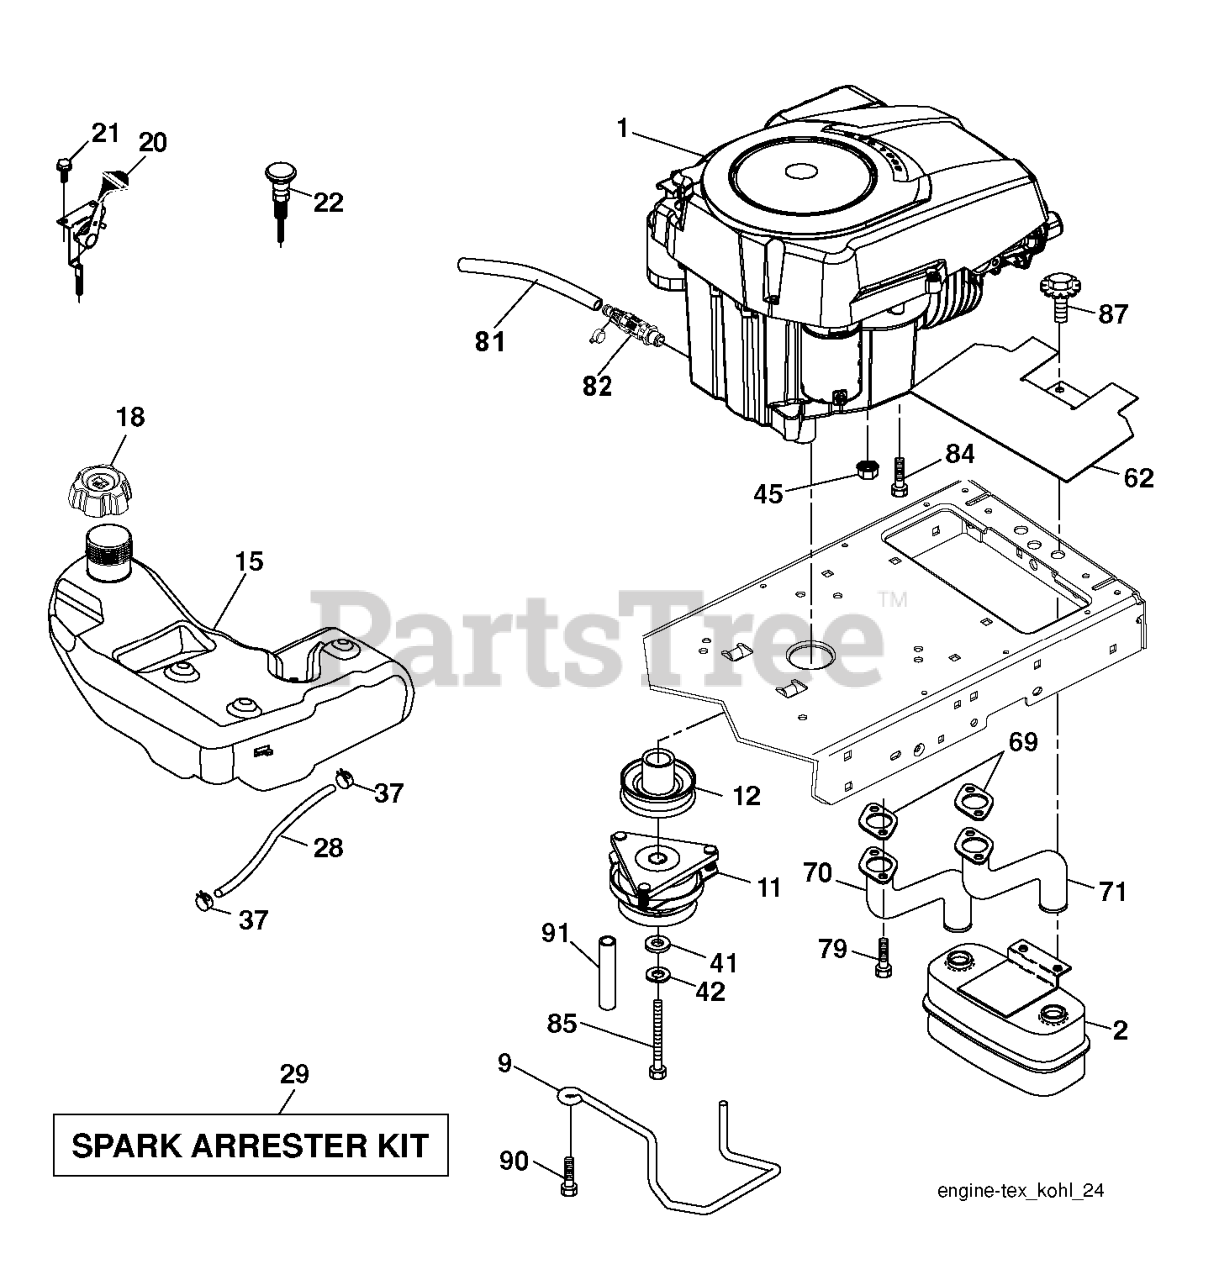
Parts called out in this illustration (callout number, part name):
2	MUFFLER.TWIN.CYL.LOW.TONE
9	KEEPER.BELT.ENGINE.4.2
11	CLUTCH.ELECTRIC.LT.48"*
12	PULLEY.ENGINE.TUFFTORQ
15	TANK.FUEL.4GAL
18	CAP.FUEL.TANK.3"GREY
20	THROTTLE CONTROL
21	SCREW.#10 X 0.750.BOS
22	CONTROL.CHOKE.ERGO.PUSH-IN.BLA
28	REPL BY 532 00 85-43
29	KIT.SPARK ARRESTOR 794945 B&S
37	HOSE CLAMP
42	LOCKWASHER
45	NUT
62	RP SHIELD HEAT MUFFLER
69	GASKET.EXHAUST.KOHL.CV18-CV26
70	RP.PIPE-EXHAUST LH
71	RP.PIPE-EXHAUST RH
79	SCREW.SOCKET HD.5/16-1
81	TUBE, DRAIN OIL ASM.
82	VALUE.OIL.DRAIN
84	SCREW 3/8-16X1
85	BOLT HEX 7/16-20X4-1/4"
87	BOLT.5/16-18UNCX3/4 W/SEMS.BLK
90	SCREW 3/8-16X1
91	BUSHING.1.375OD
